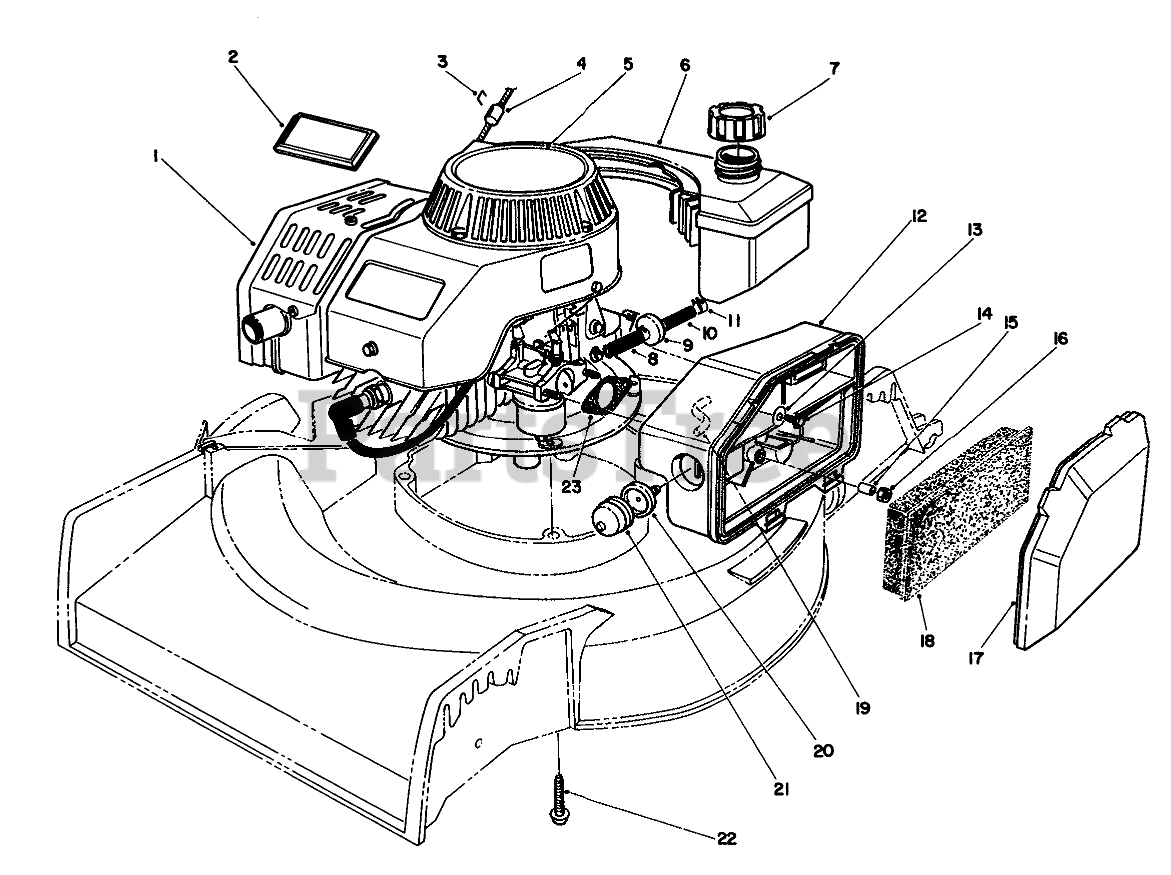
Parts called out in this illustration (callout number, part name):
1	Engine
2	TORO LOGO PLT
3	Staple
4	STOP-ROPE
5	DECAL - 2 CYC RECOIL
6	FUEL TANK ASM
7	GAS CAP ASM
8	HOSE-FUEL
9	FILTER-FUEL
10	HOSE-FUEL
11	CLAMP-FUEL LINE
12	BODY-AIR CLEANER
13	WASHER-FLAT
14	SCREW-HH
15	SPACER
17	COVER-AIR CLEANER
18	ELEMENT-AIR CLEANER
19	HOSE-PRIMER
20	BODY-PRIMER
21	BULB-PRIMER
22	SCREW-HHF, WHIZ
23	GASKET-AIR CLEANER
